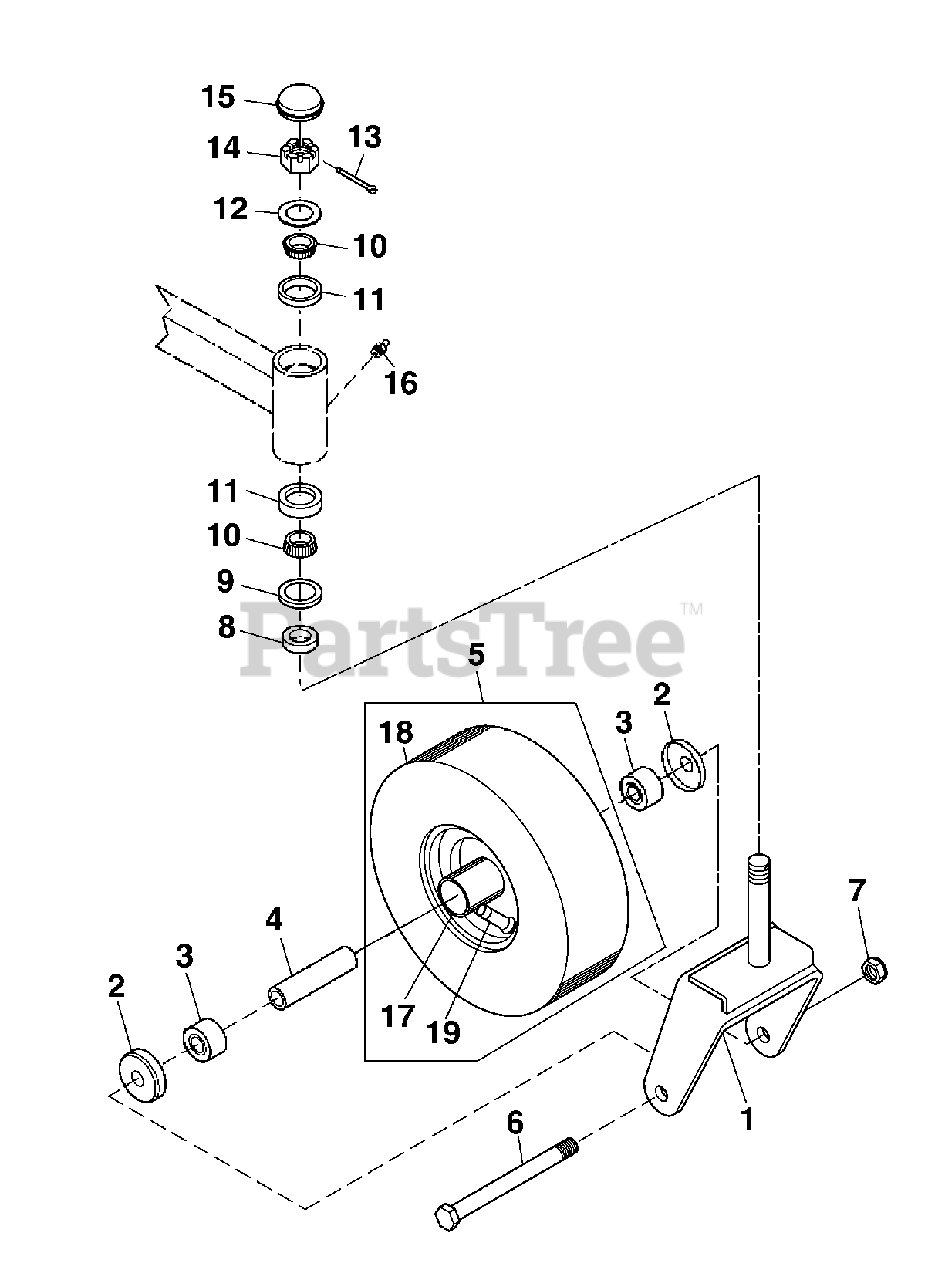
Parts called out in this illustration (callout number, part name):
1	WLDT, YOKE CASTER S/O
2	CAP, WHEEL
3	BALL BEARING
5	WHEEL/TIRE ASSEM - CASTER
6	SCREW, HEX HEAD, METRIC
7	NUT,ISO4032,M16X2-10-ZN
8	SPACER, CASTER
9	SEAL, WHEEL BEARING
10	CONE BEARING
11	CUP, 1.00 ROLLER BEARING
12	WASHER,JDS24-1.016X1.5X.134-ST
13	PIN,COTTER,DIN94,3.2X50-ST-ZN
14	NUT, 1-14 CASTLE Y
15	CAP, DUST
16	FTG, 1/4-28 STRGT GREASE ZERK
17	RIM - 6" FRONT CASTER
18	TIRE 13 X 5.00-5, 4 PLY
19	TIRE VALVE W/CAP-PUR
